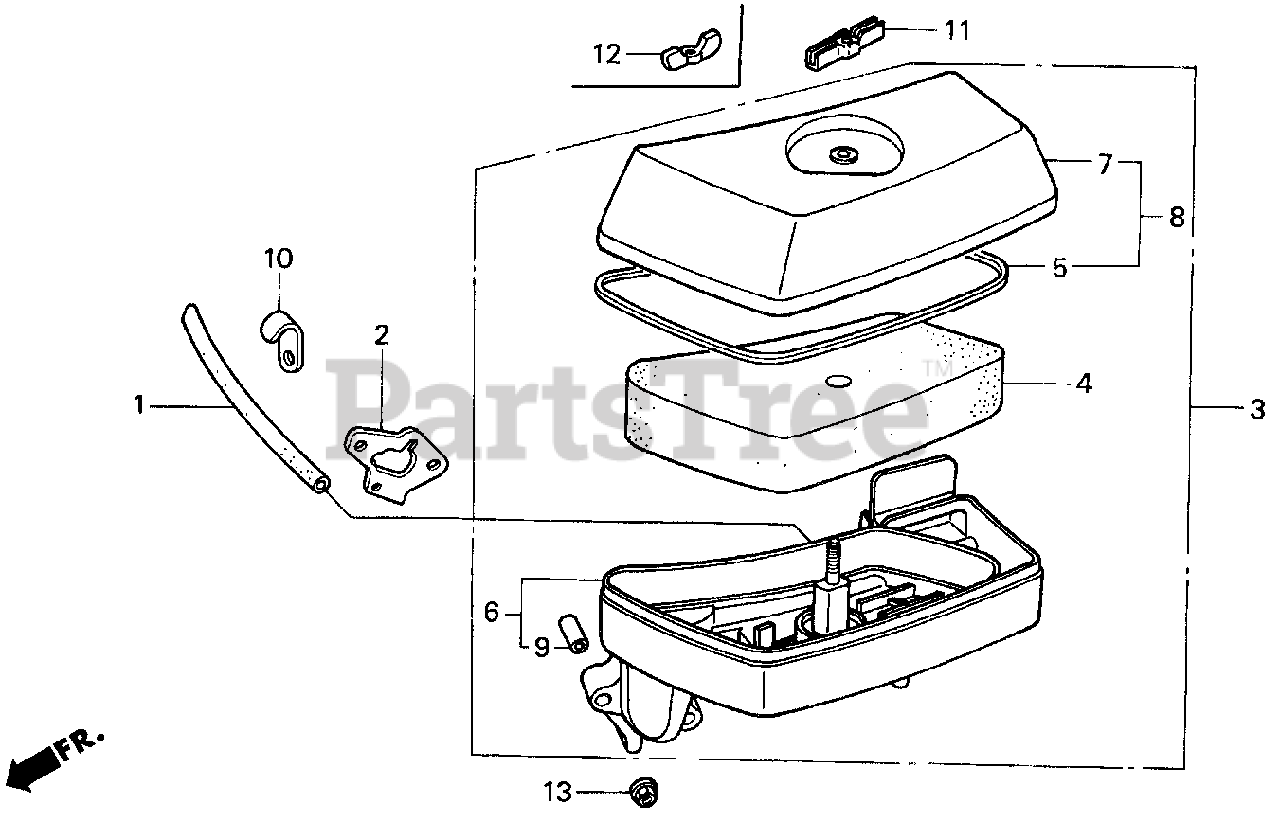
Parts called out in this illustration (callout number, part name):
1	TUBE, BREATHER
2	GASKET, AIR CLEANER
3	AIR CLEANER ASSY.
4	ELEMENT, AIR CLEANER
5	RUBBER, SEAL
6	CASE SET, AIR CLEANER *NH1* (BLACK)
6	AIR CLEANER ASSY.
6	HOUSING, AIR CLEANER
6	HOUSING, AIR CLEANER *NH1* (BLACK)
7	COVER, AIR CLEANER *NH105* (MAT BLACK)
8	COVER, AIR CLEANER *NH105* (MAT BLACK)
9	COLLAR, AIR CLEANER HOUSING (NOT AVAILABLE)
9	COLLAR, AIR CLEANER HOUSING
10	CLIP, TUBE
11	WINGNUT (6MM) (BLACK)
12	NUT, TOOL BOX SETTING
13	NUT, FLANGE (5MM)
